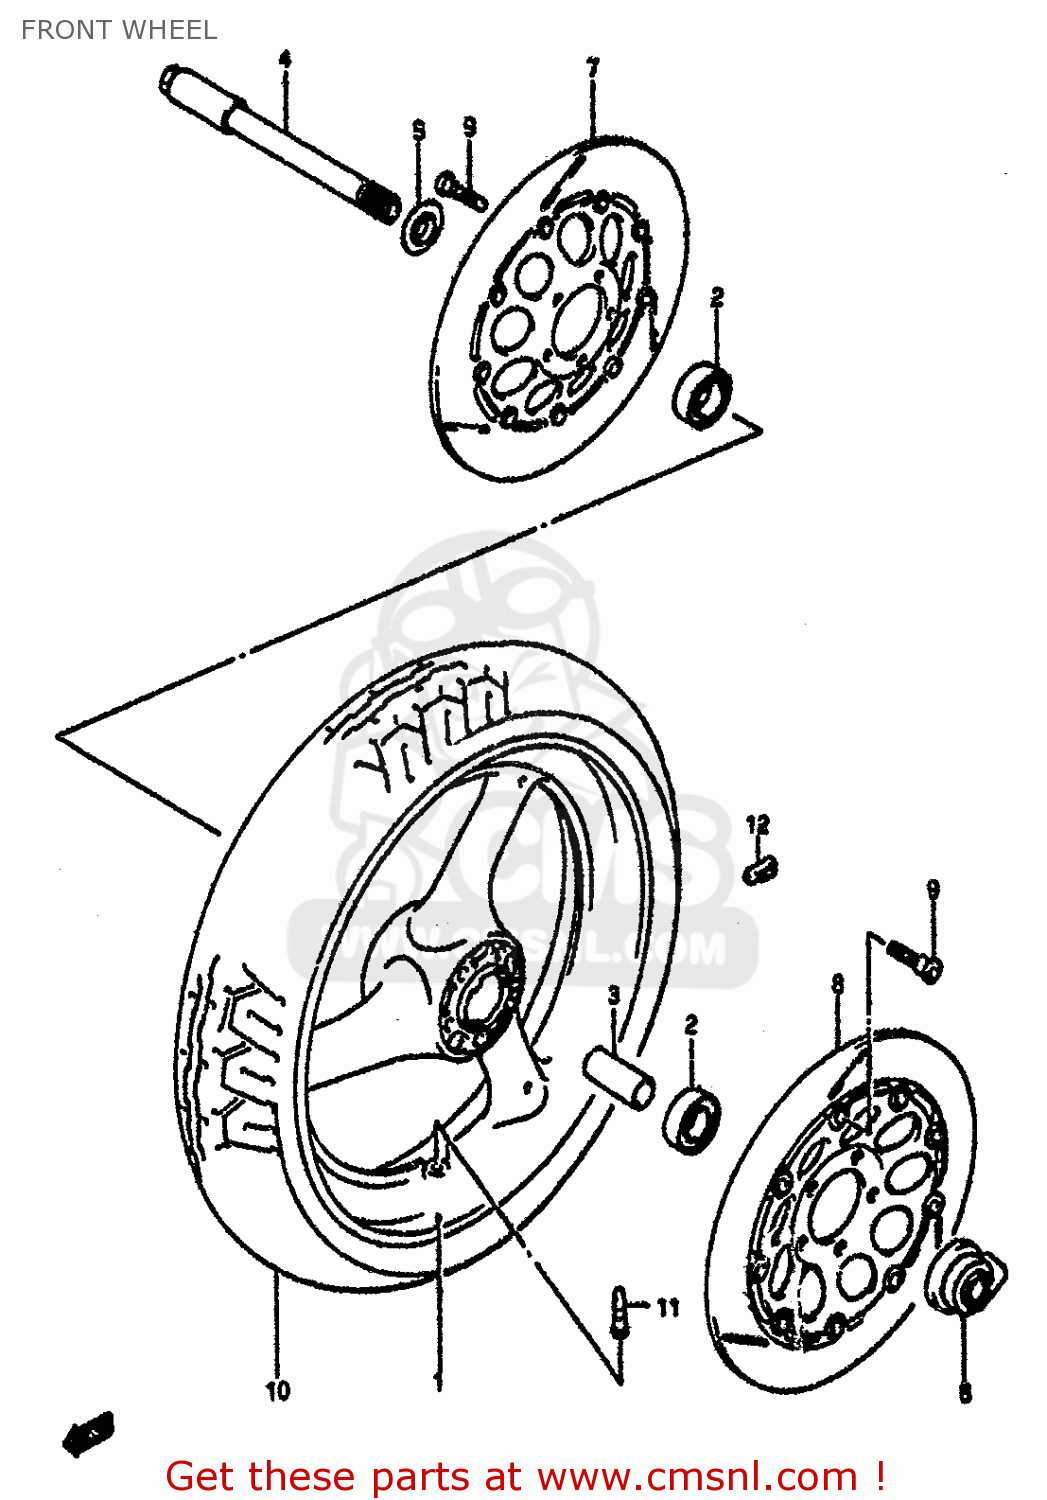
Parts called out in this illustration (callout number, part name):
1	WHEEL,FRONT
2	BEARING
3	SPACER(20.8X27.2X74)
4	AXLE,FR
5	SPACER,FR HUB BEARING,R
6	BOX ASSEMBLY,SPEEDOMETER GEAR
7	DISC,BRAKE
8	DISC,BRAKE
9	BOLT
10	TIRE,FRONT
11	VALVE ASSY,WHEEL RIM(TR412)
12	BALANCER,WHEEL
